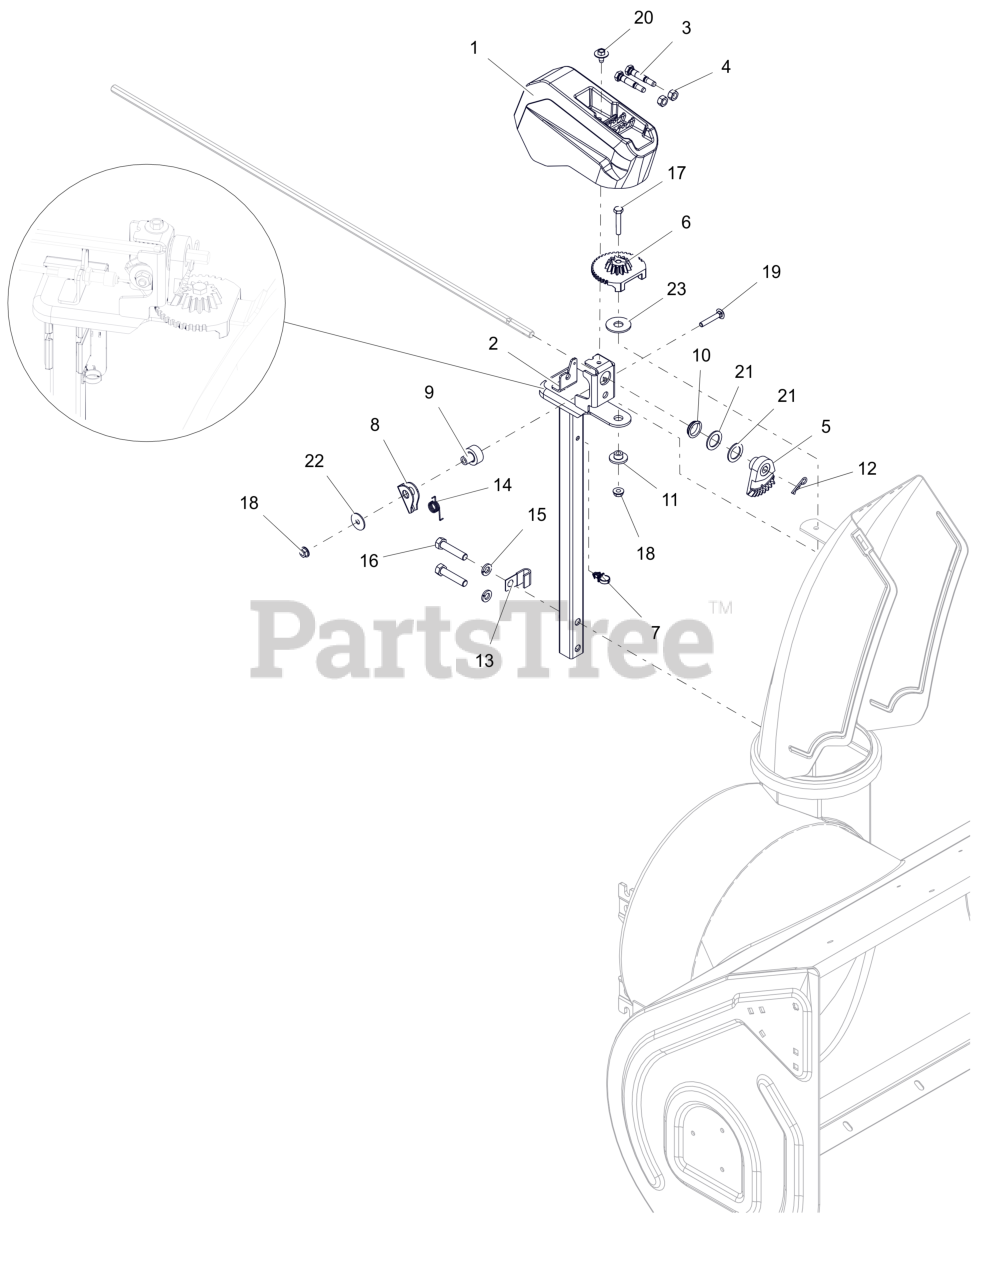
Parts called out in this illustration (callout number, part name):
1	COVER, CHUTE PEDESTAL
2	PEDESTAL, CHUTE - QUICK STICK
3	SHEAR BOLT SERVICE ASSEMBLY
4	NUT,LK-CTR .31-18 GA ZCC
5	GEAR, CHUTE-ACTUATION
6	GEAR, CHUTE
7	CLIP, CABLE GUIDE
8	ARM, LOCKING
9	BUSHING, LOCK ARM
10	BUSHING, POLYLINER-.75 SNAPIN
11	BSHG-FLG .265X.477X.375X1.00
12	PIN, HAIR #213 .08X1.19 ZCC
13	J-CLAMP
14	SG-TORS
15	WSHR,LK-REG .375X.094 ZCC
16	BLT, HEX .38-16X1.75 G5 ZCC
17	BLT, HEX .25-20X1.50 G5 ZCC
18	NUT-LK-CTR-FLG .25-20 ZC120
19	BLT, RHSN .25-20X1.50 G5 ZCC
20	SCR, TAP .25-20X.50 LG HWH ZCC
21	WSHR, FLT .754X1.125X.062 ZCC
22	WSHR,FLT .281X1.000X.063 ZCC
23	WSHR-FLT-NYL .515X1.375X.093
